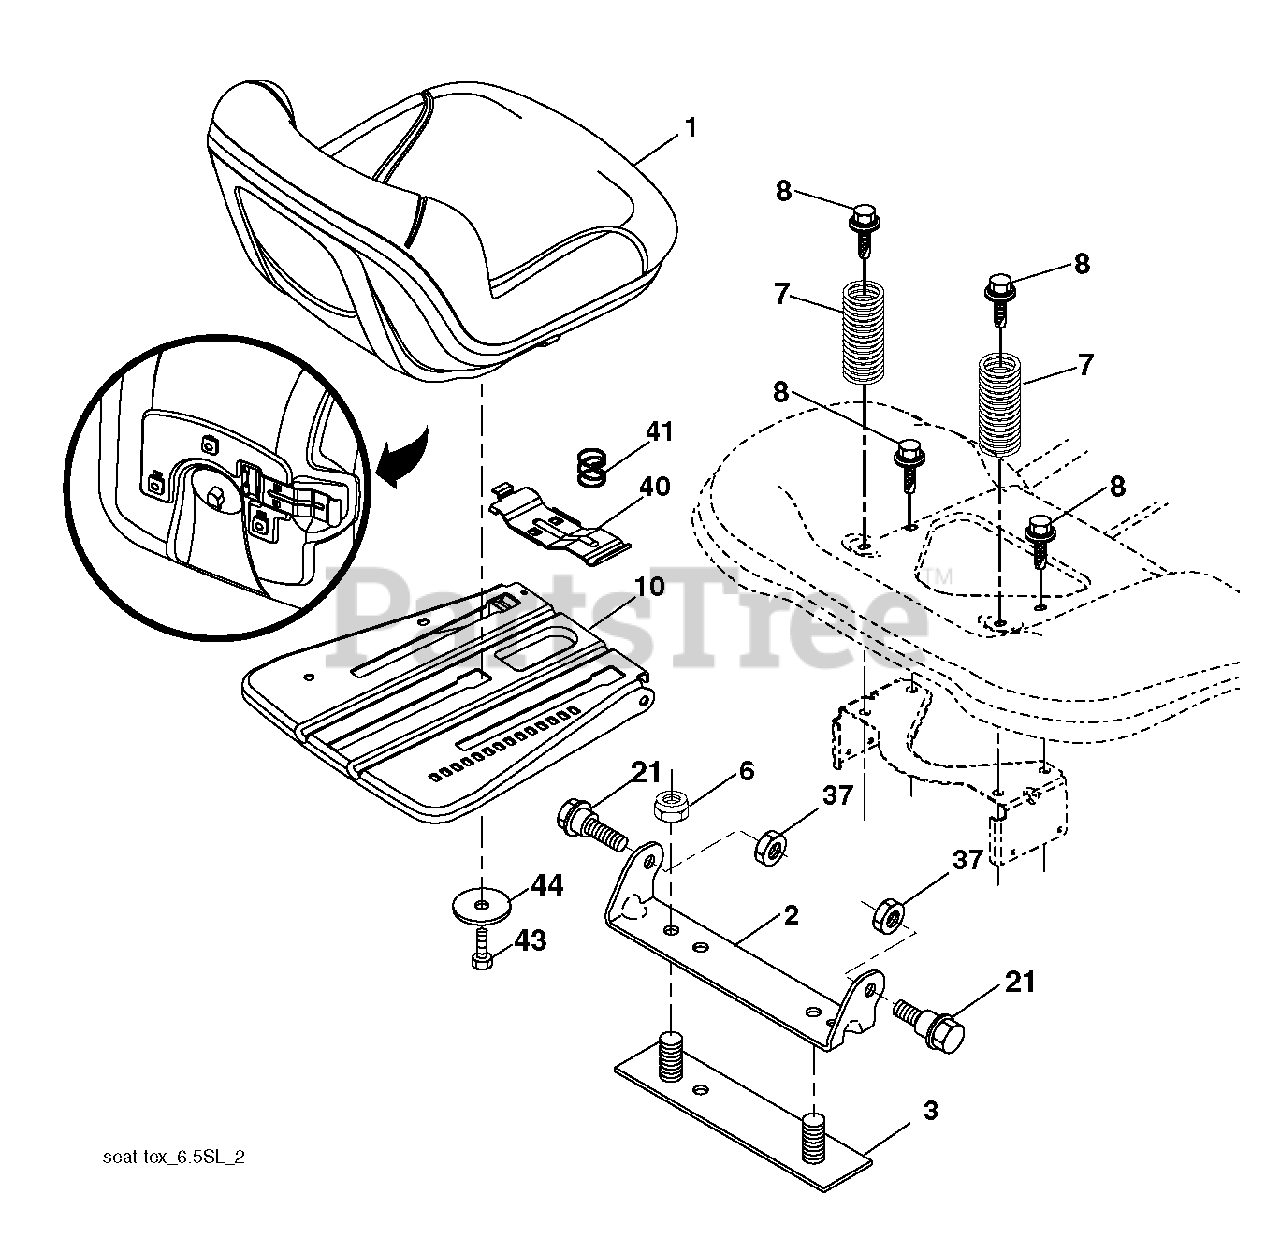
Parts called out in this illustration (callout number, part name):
2	BRKT.PIVOT.FENDER
3	STRAP
7	SPRING COMPRESSION
8	BOLT, 5/16-18 X 1 3/4
10	PAN.ASM.SEAT.3PT
21	BOLT, SHOULDER
40	HANDLE.SLIDE.SEAT.TEX.
41	SPRING.LATCH.SEAT.TEX
44	WASHER 13/32 X 2-3/8 X 12GA
